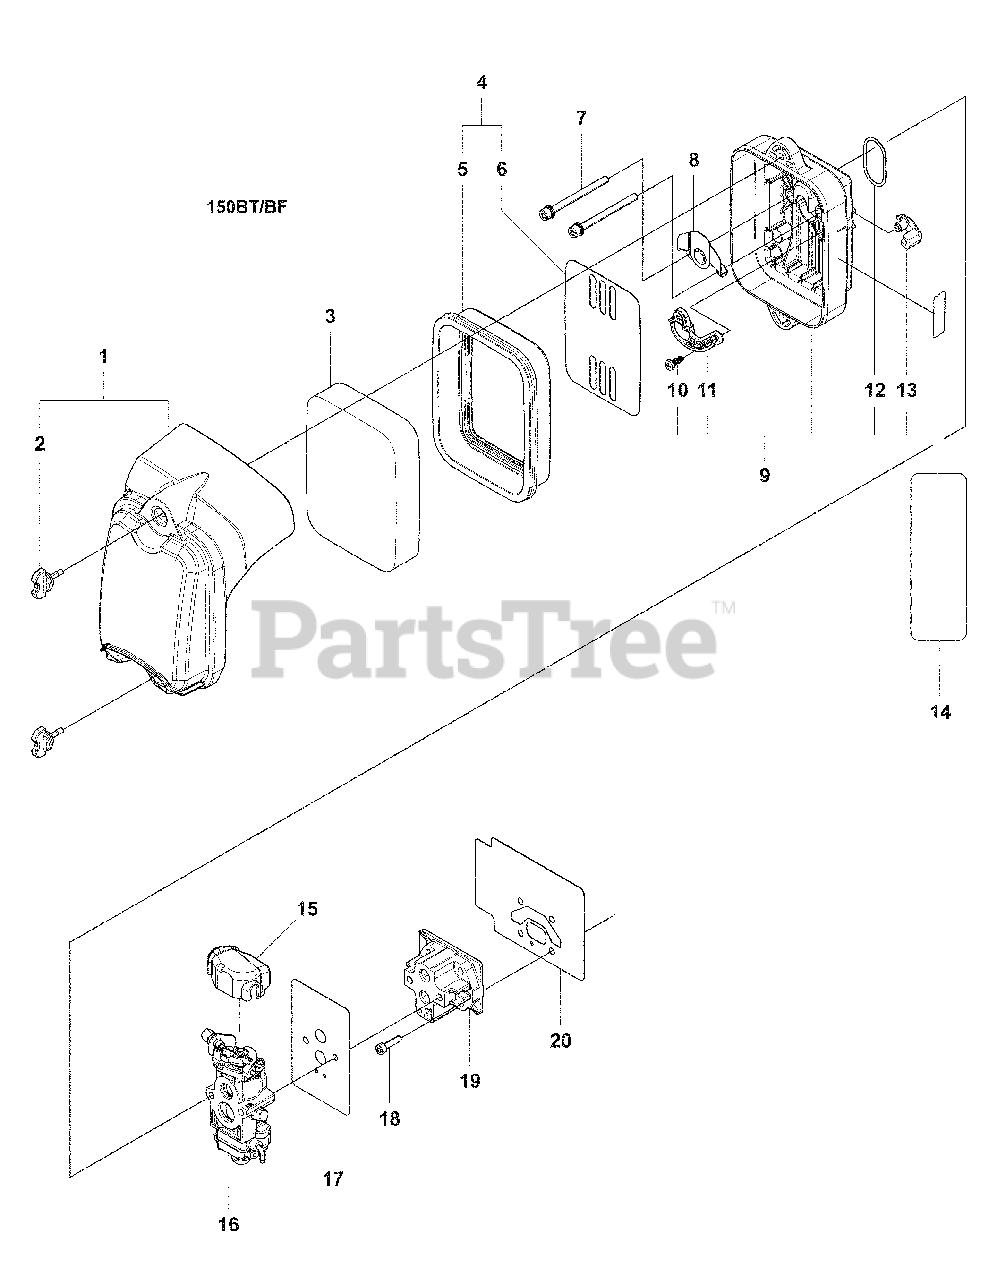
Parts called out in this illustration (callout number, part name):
3	Air Filter
9	Air Filter Holder Assembly
14	RP_LABEL, HOTMARK
15	Cover
16	Carburetor
17	Carburetor Gasket
18	Bolt
19	Insulation
20	Insulator Gasket
